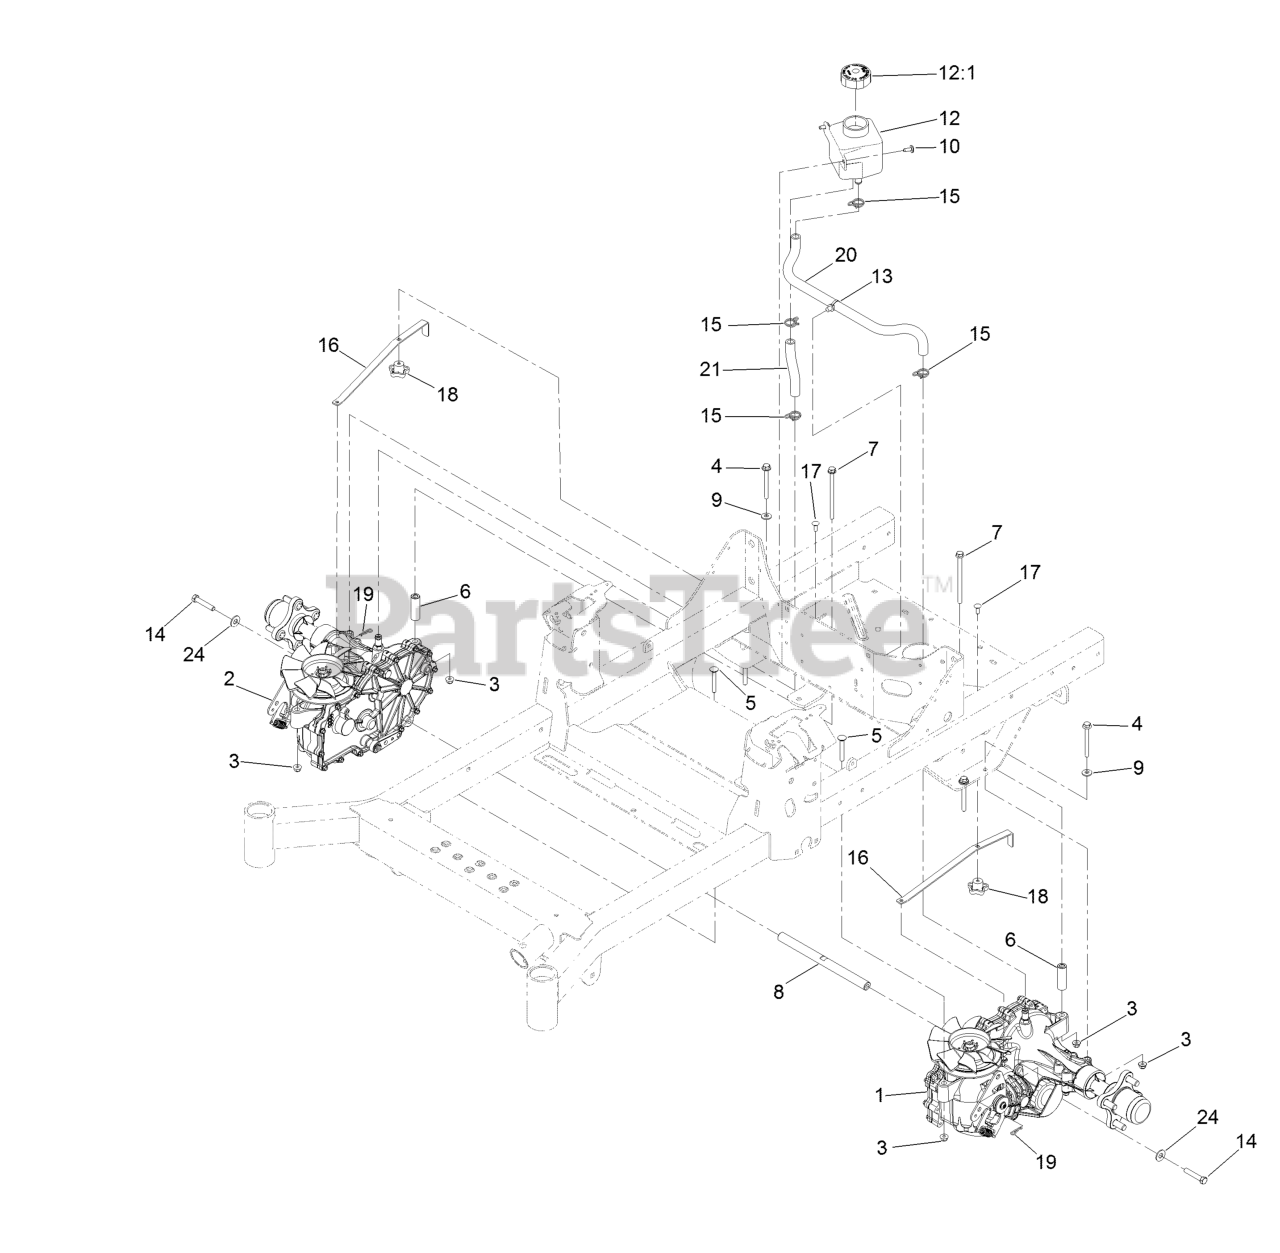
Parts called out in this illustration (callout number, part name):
1	LH Transaxle ASM
2	RH Transaxle ASM
3	Nut-Flange, NI
4	Screw-HHF
5	Bolt-CARR
6	Spacer-Hydro
7	Screw HHF
8	Shaft-Spacer
9	Washer-Spring
10	Screw-Torx
12	Vent-Tank, HYD
12:1	Cap-Reservoir, HYD
13	Clip-Tie
14	Screw-HH W/Loctite
15	Clamp-Hose
16	Arm-Bypass, Hydro
17	Bolt-CARR
18	Knob-Handle
19	Pin-Cotter
20	Hose-Hydraulic
21	Hose-Hydraulic
24	Washer-Flat
